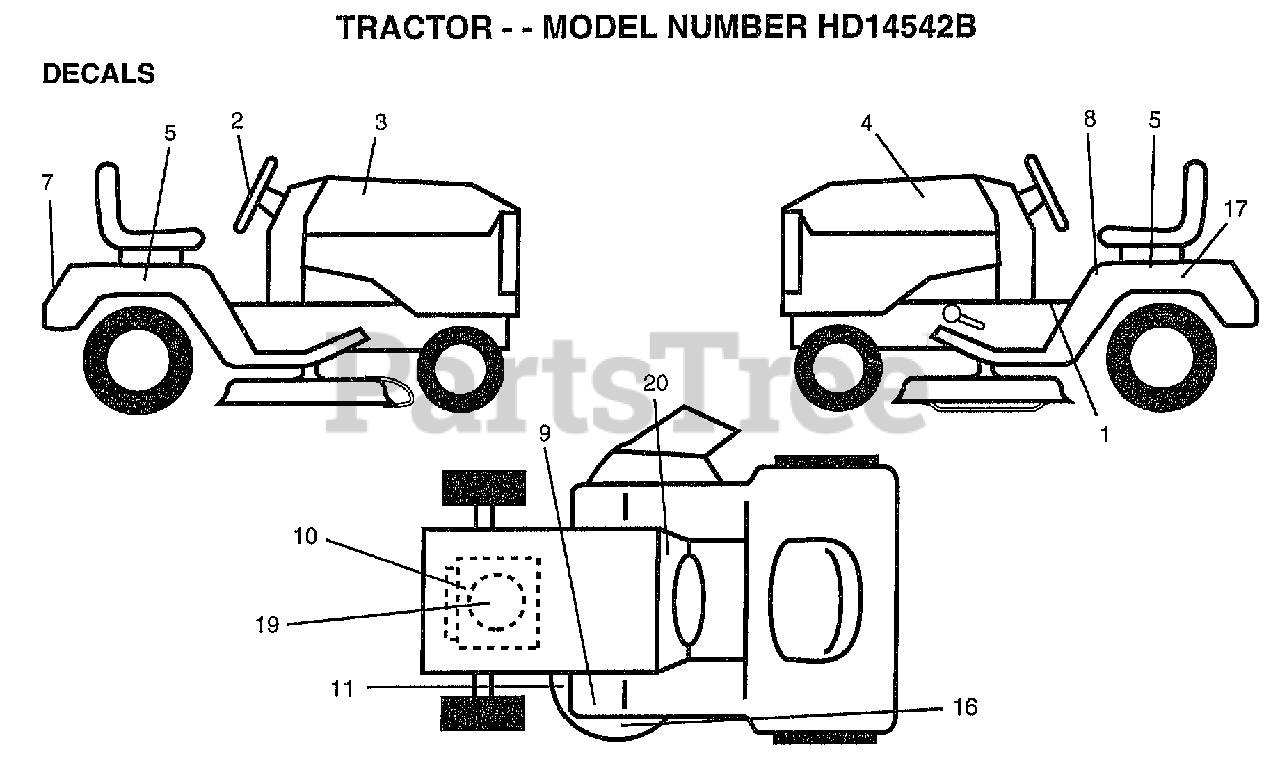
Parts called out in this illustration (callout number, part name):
2	"DECAL WHEEL,STEER"
3	DECAL HOOD RH
4	DECAL HOOD LH
5	DECAL.FENDER.SD.LAWN
7	"DECAL FENDER,LOGO"
8	"DECAL FENDER,DANG"
9	DECAL CLUT/BRAKE
10	DECAL.ENGINE
11	"DECAL-SCHEM,BELT"
16	"DECAL DECK,MULCH"
17	DECAL.BATRY.3-3908
19	DECAL.REPLACEMENT.ENG
20	DECAL DASH PNL
